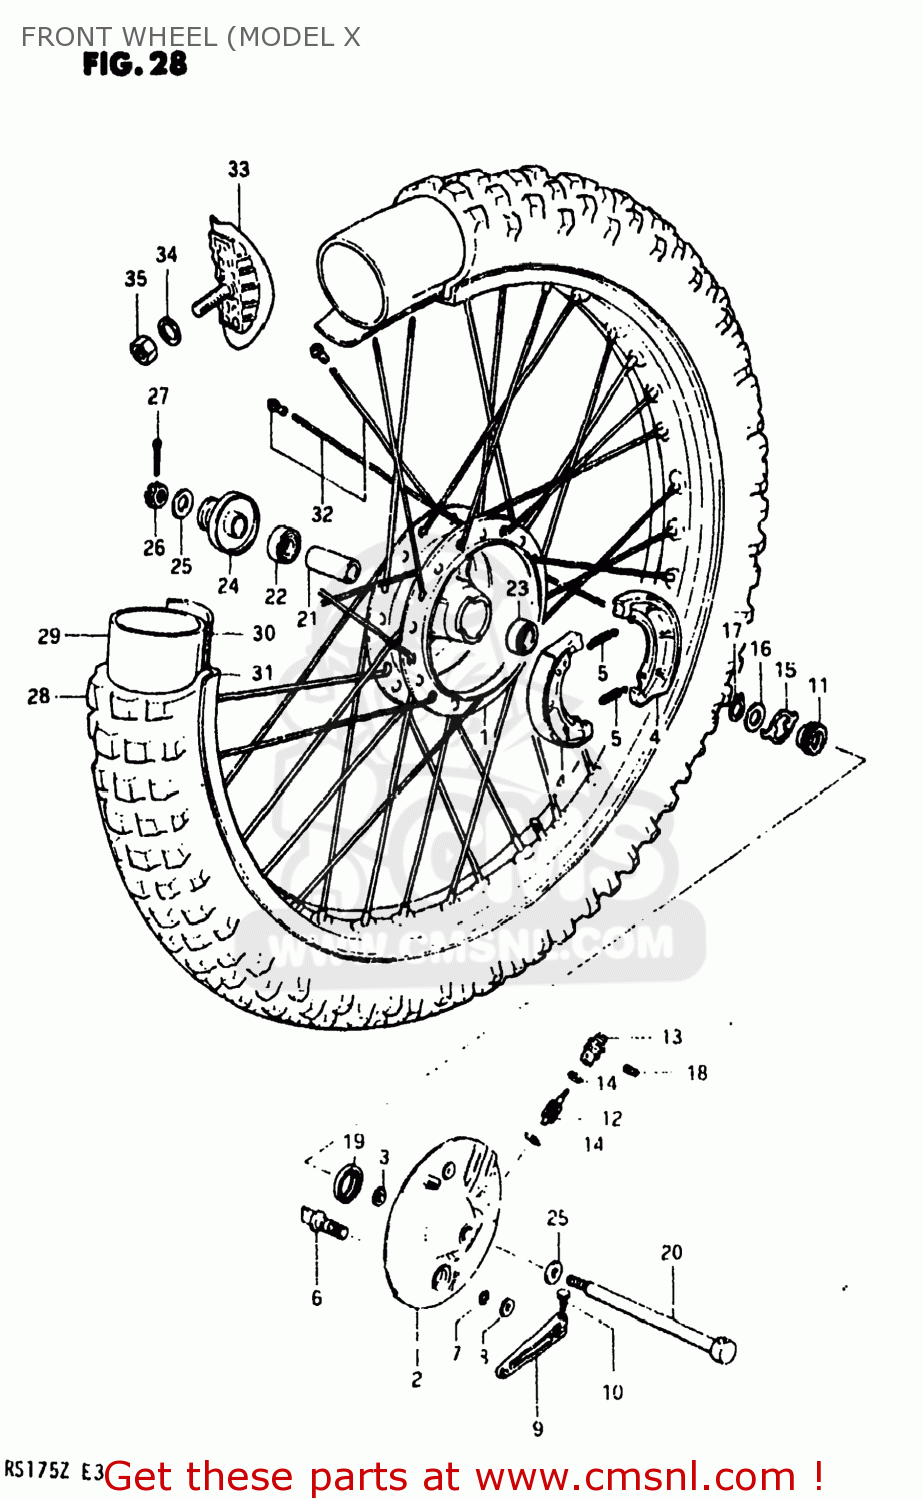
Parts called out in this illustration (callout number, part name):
1	HUB,FRONT
2	PANEL,FRONT HUB
3	BOSS
4	SHOE,BRAKE
5	SPRING(L:34)
6	CAM,FRONT BRAKE
7	O-RING (D:2.4 ID:13.8)
8	WASHER (14.5X22X1.6)
9	LEVER,FRONT BRAKE CAM
10	BOLT
11	GEAR,SPEEDOMETER
12	PINION,SPEEDOMETER
13	BUSH,METER GEAR OUTER
14	WASHER (5.1X9X0.4)
15	DRIVER,SPEEDOMETER GEAR
16	WASHER(18.5X24X1)
17	CIRCLIP
18	SCREW
19	OIL SEAL (43X58X7)
20	AXLE,FRONT
21	SPACER (12.6X19X52)
22	BEARING, RH
23	BEARING
24	SPACER,FRONT AXLE,RIGHT
25	WASHER
26	NUT, REAR AXLE
27	COTTER PIN
28	TIRE,FRONT
29	TUBE,INNER
30	PROTECTOR,WHEEL,INNER
31	RIM,FRONT WHEEL
32	SPOKE SET,FRONT
33	STOPPER,BEAD
34	WASHER
35	NUT
